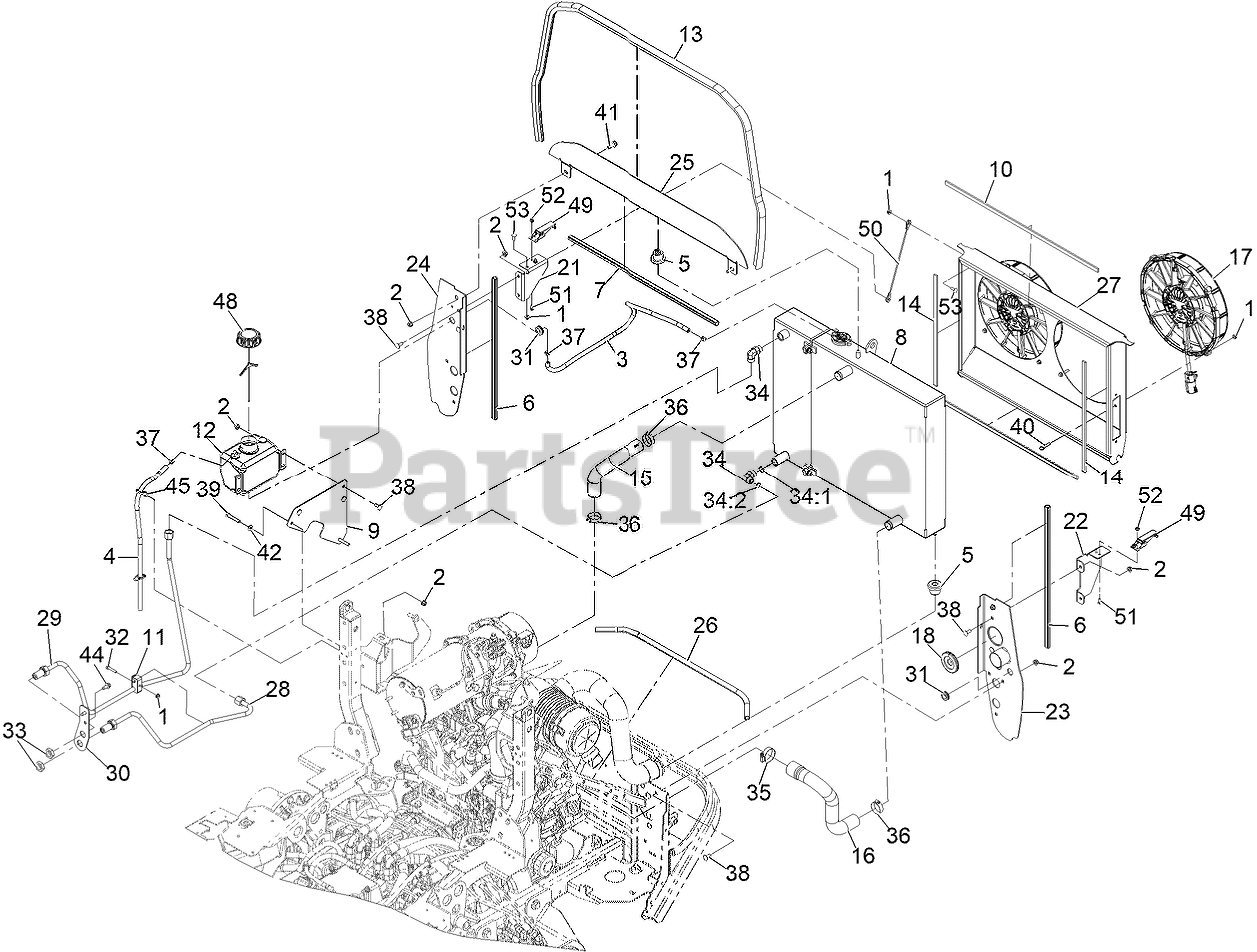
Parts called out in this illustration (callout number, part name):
2	NUT-HF, NI
3	HOSE-FUEL
4	HOSE-FUEL
5	MOUNT-ISOLATOR
6	SEAL-BULB
7	SEAL-BULB
8	COOLING ASM
9	BRACKET-BOTTLE
10	FOAM-ADHESIVE BACKED
11	CLAMP-TWIN
12	TANK-OVERFLOW, W/CAP
13	SEAL-BULB
14	FOAM-ADHESIVE BACKED
15	HOSE-RADIATOR, UPPER
16	HOSE-RADIATOR, LOWER
17	FAN-12", 12V, ELECTRIC, REVERSING
18	GROMMET-SPLIT, 2.38 GD X 0.14 GW X 0.82
21	BRACKET-SHROUD LATCH RIGHT
22	BRACKET-SHROUD LATCH LEFT
23	SUPPORT-RADIATOR, LH [BLACK]
24	BRACKET-COOLING, RH
25	BRACKET-COOLING, TOP
26	SEAL-BULB
27	FAN SHROUD
28	HYDRAULIC TUBE ASM
29	HYDRAULIC TUBE ASM
30	BRACKET-BULKHEAD
31	GROMMET
32	SCREW-HH
33	NUT-BULKHEAD
34	FITTING-ELBOW, 90 DEG
34:1	O-RING
34:2	O-RING
35	CLAMP-HOSE
36	CLAMP-HOSE
37	CLAMP-HOSE
38	SCREW-CARR
39	SCREW-HH
40	SCREW-HHF
41	SCREW-HHF
42	WASHER-PLAIN
44	Screw-HWH 5/16-18 X 3/4 Tf
45	CLIP-TIE
48	CAP-W/TETHER
49	LATCH-DRAW
50	CABLE-STOP, SEAT
51	BOLT-CARR
53	BOLT-CARR
